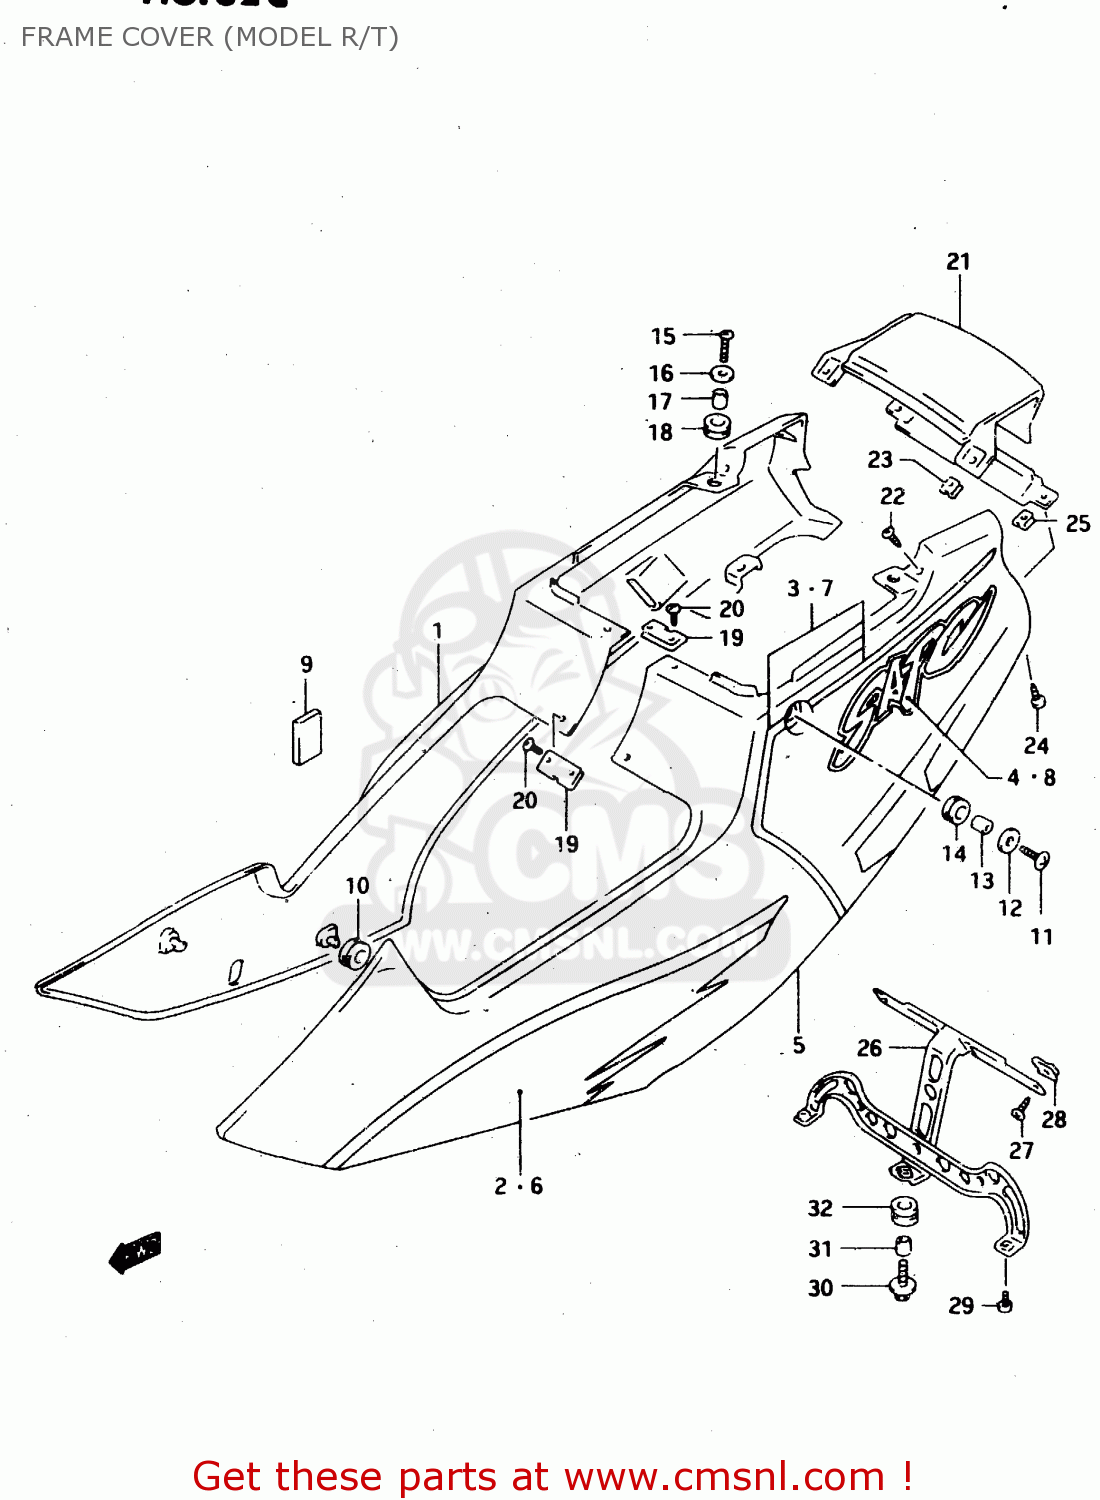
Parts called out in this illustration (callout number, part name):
1	COVER,FRAME,R(WHITE)
2	TAPE, FRAME COVER RH
3	TAPE, ZECKEN RH
4	EMBLEM,FRAME COVER
5	COVER,FRAME,L(GRAY)
6	TAPE,FRAME COVER STRIPE,L
7	TAPE,STICKER LH
8	EMBLEM,FRAME COVER
9	TAPE,FRAME PROTECTOR
10	CUSHION
11	SCREW
12	WASHER(6.5X22X1.6)
13	SPACER (6.3X9.1X6.7)
14	CUSHION
15	SCREW
16	WASHER(6.5X20X1.6)
17	SPACER (6.3X9.1X6.7)
18	CUSHION
19	NUT,FRAME COVER CTR
20	SCREW
21	COVER,FRAME CN
22	SCREW
23	NUT
24	SCREW
25	NUT
26	BRACKET,TAIL LAMP RR
27	SCREW
28	NUT
29	SCREW
30	BOLT(6X20)
31	SPACER (6.1X8X9.5)
32	CUSHION
